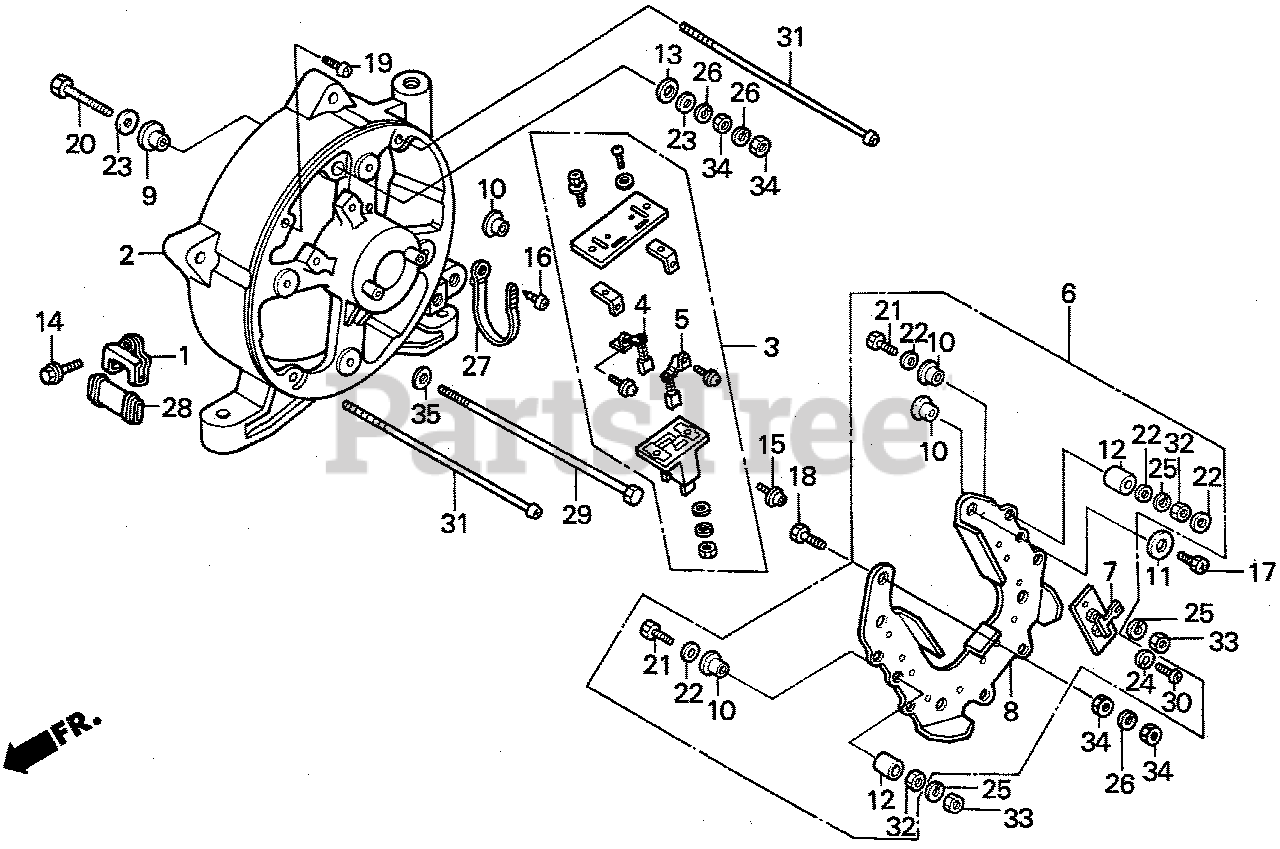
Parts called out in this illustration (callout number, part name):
1	CLIP, WIRE
2	HOUSING, RR.
3	HOLDER ASSY., BRUSH
6	DIODE ASSY.
8	PLATE, HEAT SINK
9	BUSH, INSULATING (6MM)
10	BUSH, INSULATING (5MM)
11	WASHER, INSULATING
12	INSULATOR (5MM)
13	WASHER, INSULATING
14	BOLT, FLANGE (6X12) (CT200)
15	SCREW, TAPPING (4X10)
16	SCREW, TAPPING (5X14)
17	SCREW, TAPPING (5X16)
18	BOLT, HEX. (6X16)
19	SCREW, PAN (5X12)
20	BOLT, HEX. (6X30)
21	BOLT, HEX. (5X35) (NOT AVAILABLE)
22	WASHER, PLAIN (5MM) (NOT AVAILABLE)
23	WASHER, PLAIN (6MM)
24	WASHER, SPRING (4MM)
25	WASHER, SPRING (5MM)
26	WASHER, SPRING (6MM)
27	TIE, CABLE
28	TUBE, WIRE
29	BOLT, HEX. (6X175)
30	SCREW, PAN (4X8)
31	BOLT, HEX. (5X215)
32	NUT, HEX. (5MM)
33	NUT, HEX. (5MM)
34	NUT, HEX. (6MM)
35	WASHER, PLAIN (6MM)
